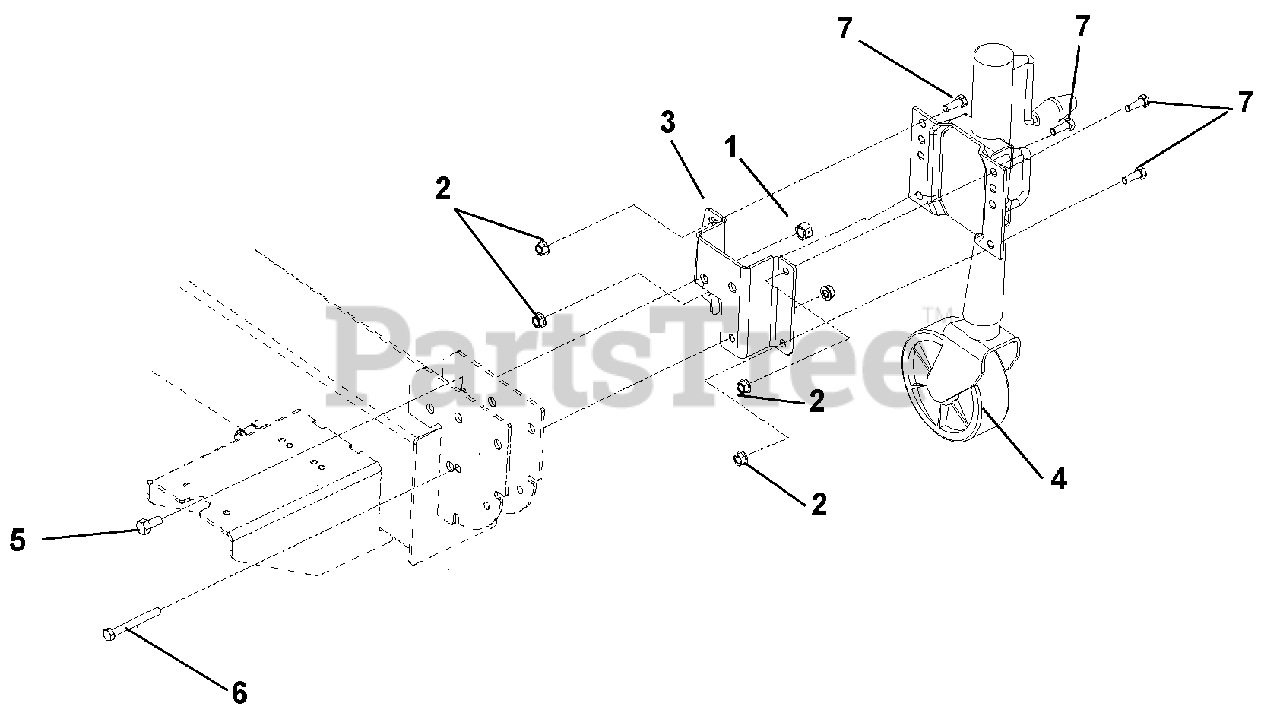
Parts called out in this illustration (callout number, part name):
1	@BLT-HEX .38-16X1.00 GR5 YWZC
2	@NUT-LK-TOP-FLG .38-16 YWZC
3	BRACKET, MOUNTING
4	STAND, JACK-W/WHEEL
5	@BLT-HEX .50-13X1.00 GR5 YWZC
6	@BLT-HEX .38-16X3.25 GR5 YWZC
7	NUT-LK-CTR-FLG .50-13 YWZC
